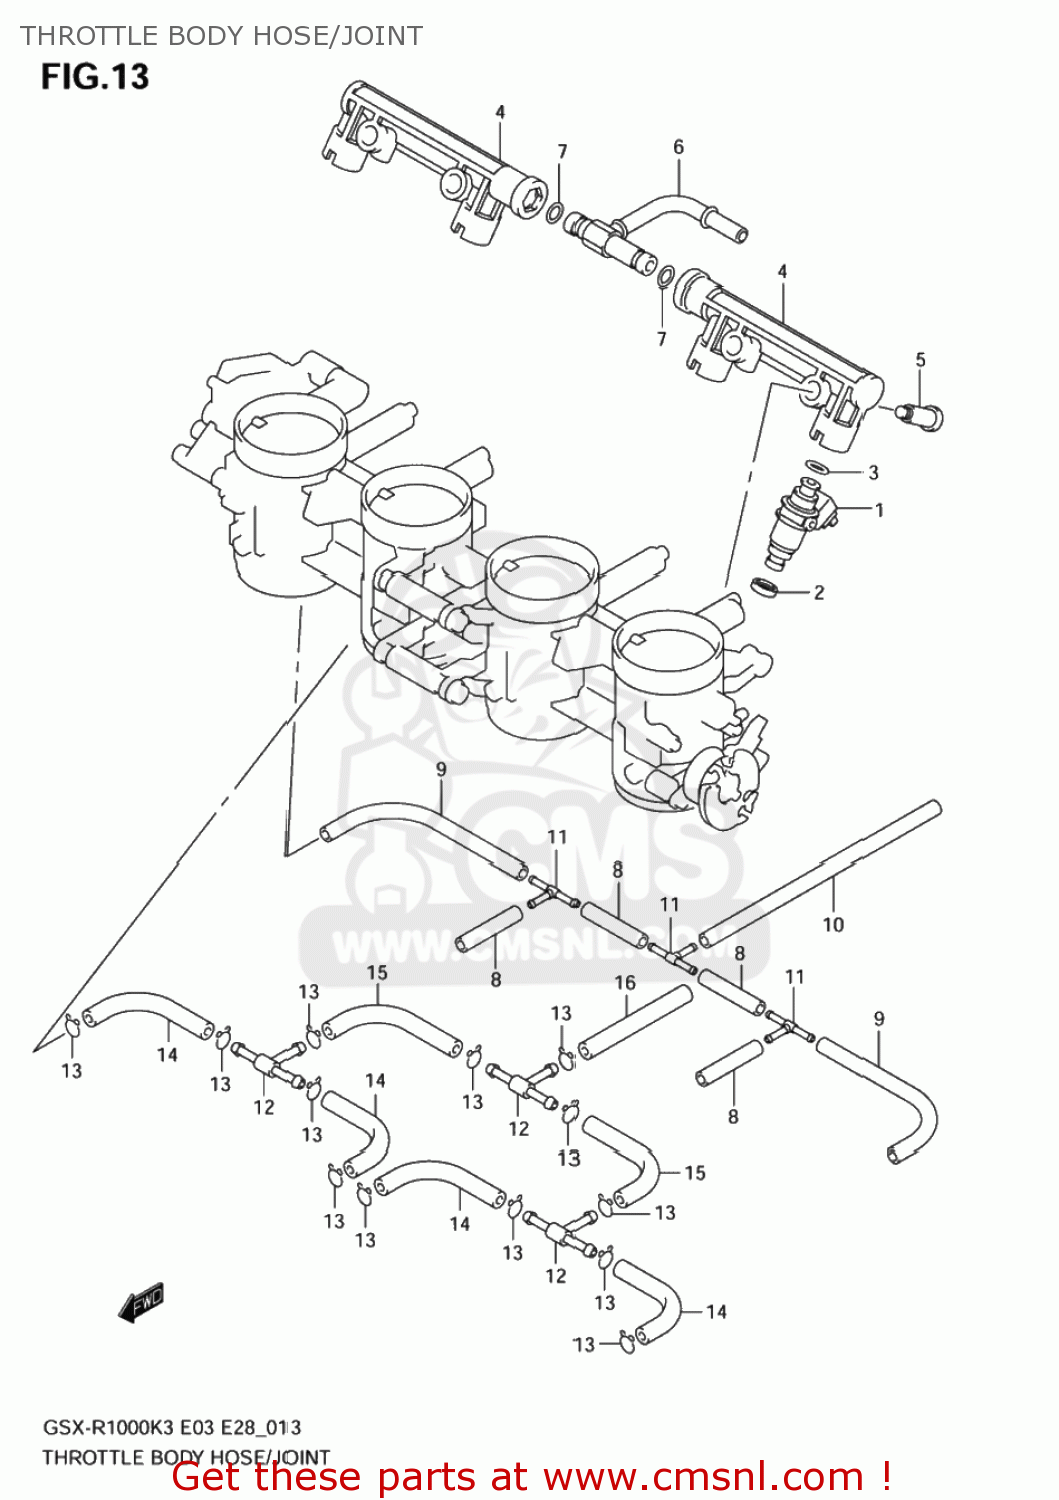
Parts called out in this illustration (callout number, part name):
1	INJECTOR ASSY
2	O RING
3	O RING
4	PIPE,FUEL
5	SCREW
6	JOINT
7	O RING
8	HOSE,RUBBER(L:35)
9	HOSE,RUBBER(L:100)
10	HOSE,RUBBER(3X7X170)
11	JOINT
12	JOINT
13	CLIP
14	PIPE
15	PIPE
16	PIPE
